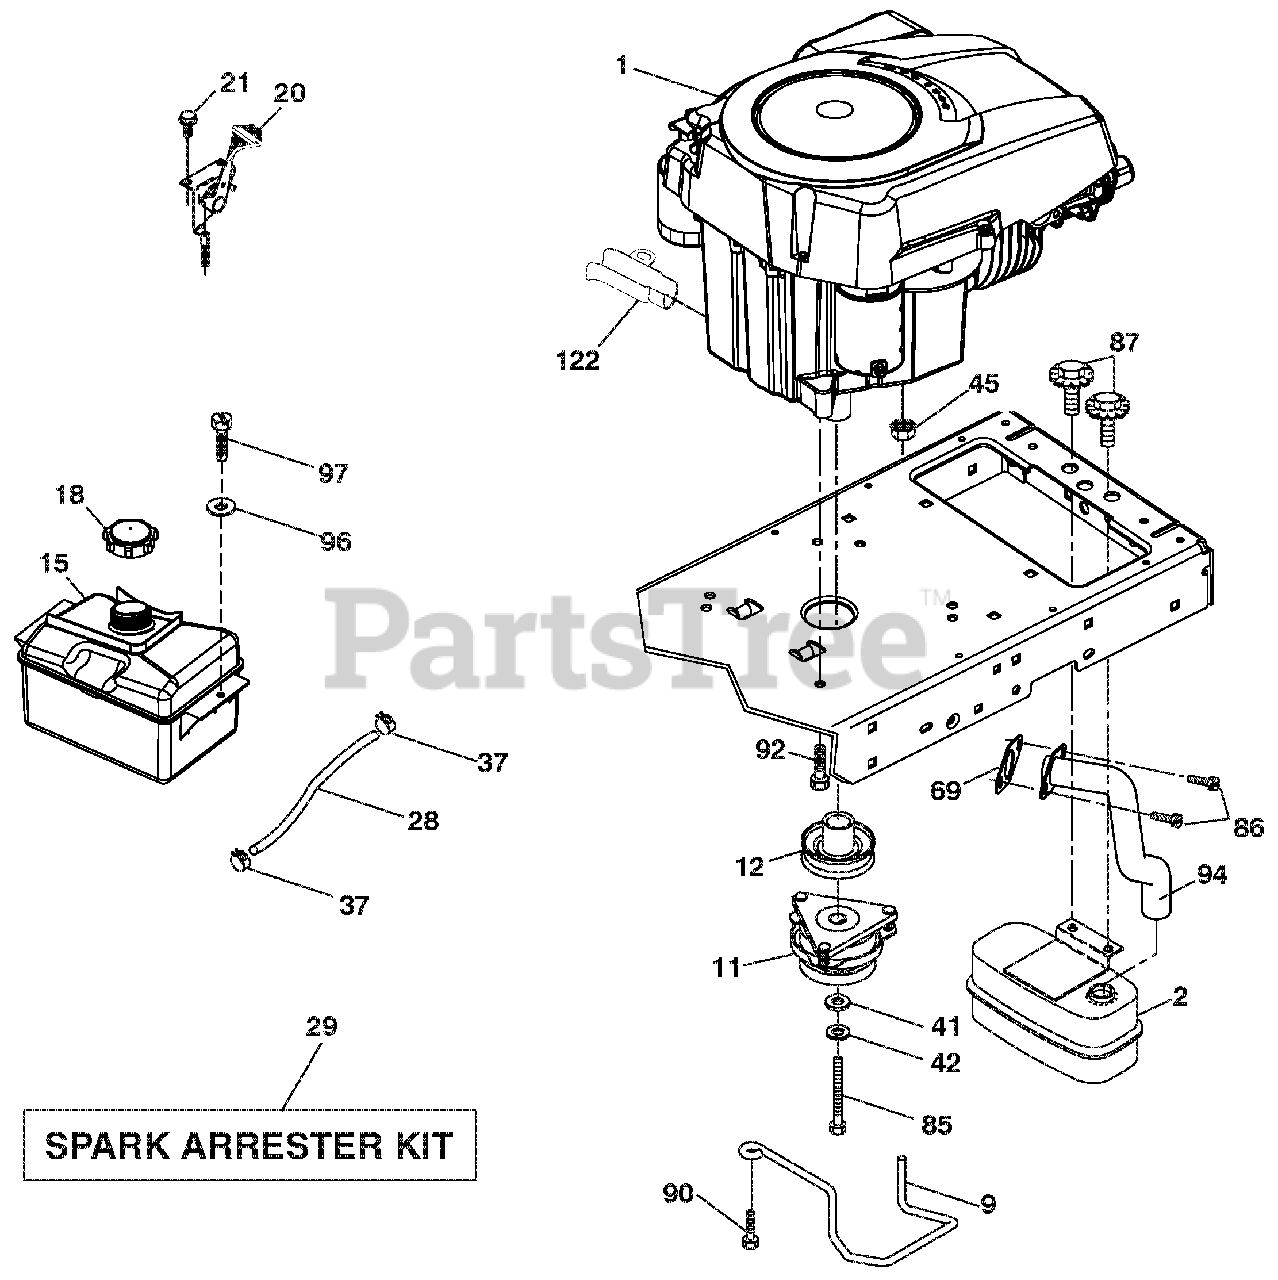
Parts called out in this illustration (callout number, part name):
1	ENGINE SV590 3229
2	MUFFLER.SINGLE.CYL.KOHL.COURAG
9	KEEPER.BELT.ENGINE.4.25"NSTG
11	CLUTCH OGURA
12	PULLEY.ENGINE.TUFFTORQE.1"CRK.
15	TANK FUEL SIDE FILL 3.00 GA.
18	CAP FUEL
20	CONTROL THROTTLE/CHOKE
28	LINE.FUEL.22"FRONT.EMIS.CA.LP
29	KIT.SPARK ARRESTOR(392390 B&S)
37	CLAMP.HOSE.BLK.
41	WASHER.1-1/2 ODX15/32 IDX.250
42	WASHER.LOCK.HVY HLCL.SPR.7/16
45	Nut, Keps Hex 1/4-20 unc
69	GASKET.KOHLER.SV.I.
85	BOLT.HEX.7/16-20X4XGR5-1.5THR.
86	SCREW SOCKET HEAD 5/16-18 X 1
87	BOLT.5/16-18 UNC X 1 W/SEMS.BL
90	SCREW.3/8-16X1.SMGML.TAP/R.BLK
92	SCREW.3/8-16 X 1.SMGML.TAP/R
94	TUBE.EXHAUST.KOHL.COURAGE
96	WASHER.9/32 X 7/8 X 16GA.
97	SCREW.HEXWSH.THDROL.1/4-20X3/4
122	Extension Drain Oil
